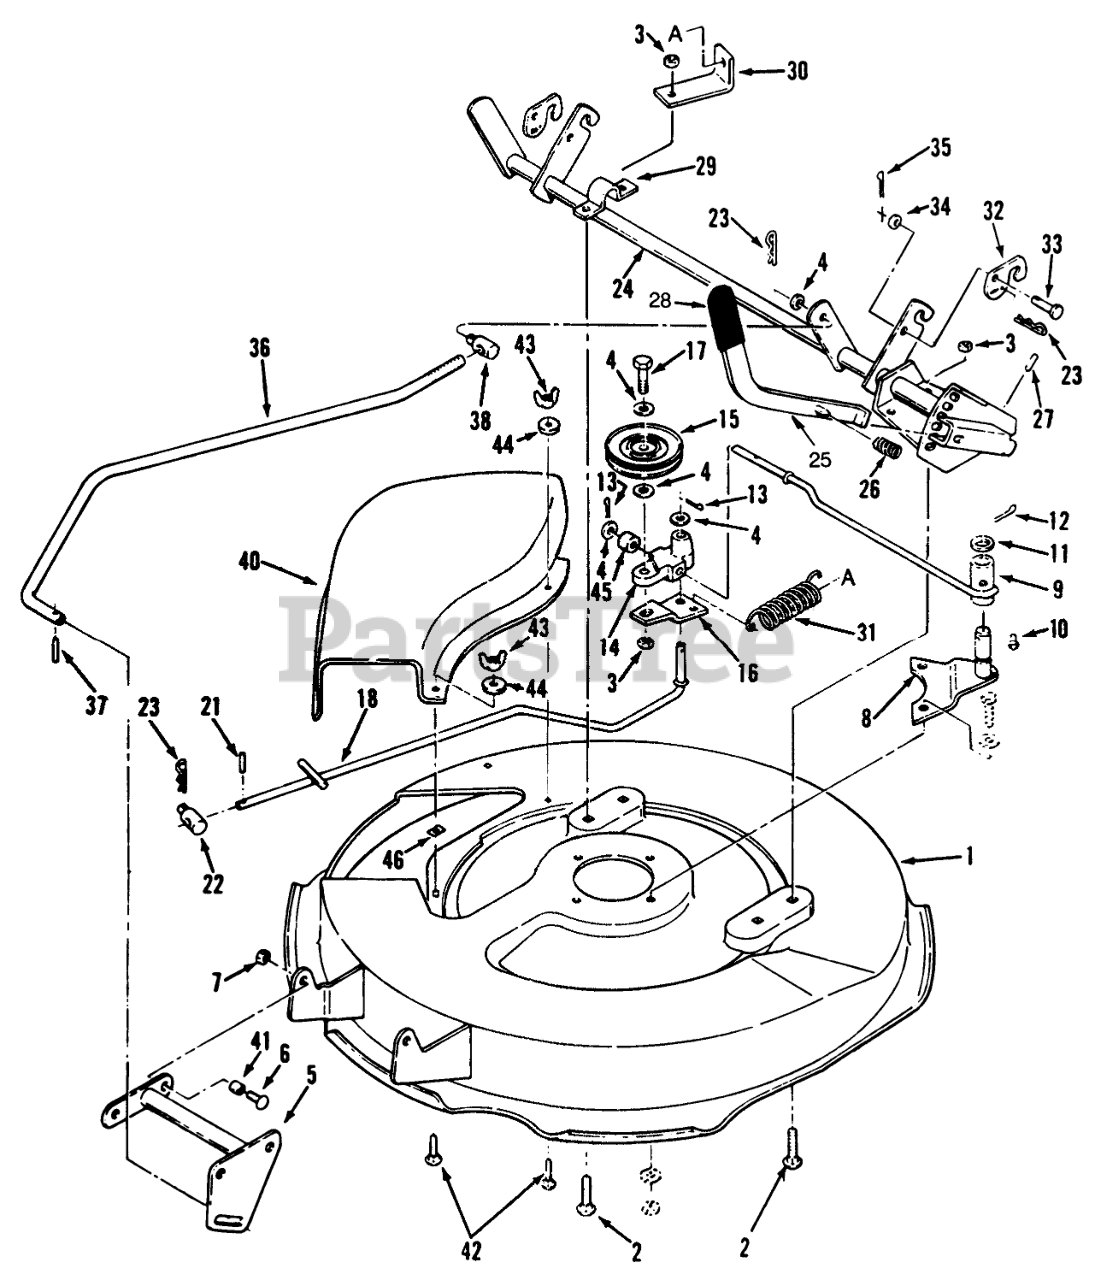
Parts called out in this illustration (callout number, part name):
1	ASM-DECK (30") R
2	Bolt
3	NUT
4	Washer
5	ASM-FRONT LIFT R
6	Bolt-Carriage
7	LOCKNUT-FLANGE
8	ASM-PIVOT, IDLER
9	WLDMT-IDLER ROD
10	Zerk
11	WASHER
12	Cotter Pin
13	Pop Rivet
14	BLOCK IDLER
15	PULLEY-IDLER V
16	ANCHOR-SPRING
17	Bolt
18	ASS'Y-IDLER ROD
21	Pin-Roll
22	TRUNNION-LIFT
23	Hairpin Cotter
24	Height Adjust Assy
25	WLDMT-LIFT LEVER R
26	SPRING-COMPRESSION
27	PIN-SPIROL
30	ANCHOR-SPRING B
31	SPRING-EXTENSION
32	LATCH B
34	Washer
35	Cotter Pin
36	ASS'Y-HEIGHT ADJ R
37	SPIROL PIN
38	STUD-TRUNION
40	Deflector
41	SPACER
42	Bolt-Carriage
43	Nut-Wing
44	WASHER
45	SPACER
46	SPEED NUT 1/4-20
